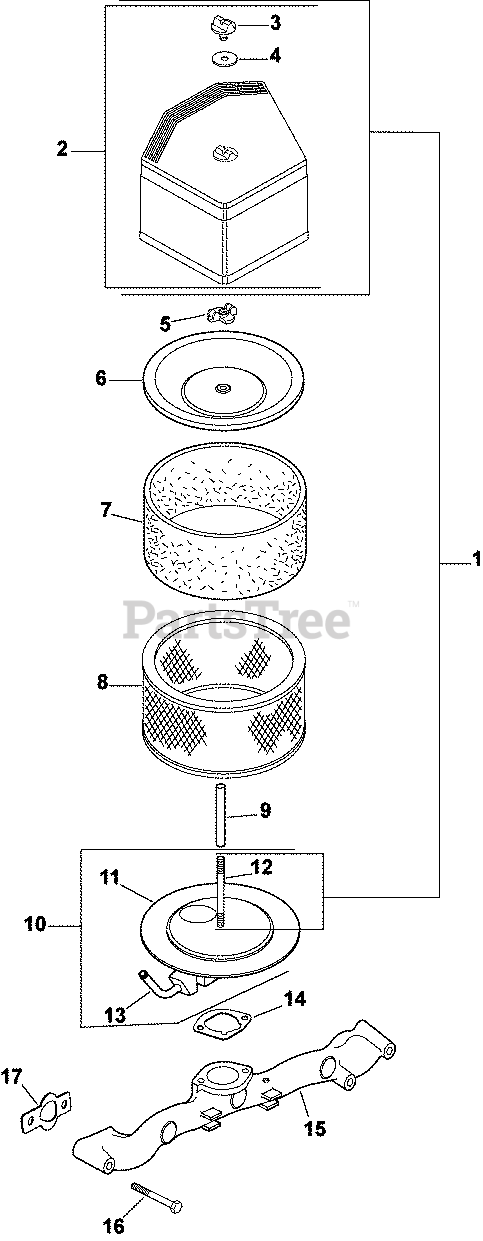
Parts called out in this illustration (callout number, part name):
1	KIT, AIR CLEANER (WAWB)
2	KIT, AIR CLEANER COVER
3	KNOB, COVER
4	GASKET, AIR CLEANER COVER KNOB
5	NUT, WING
6	COVER, INNER AIR CLEANER
7	ELEMENT, PRE-CLEANER
8	ELEMENT, AIR CLEANER - Also available Retail Packaged 45 883 02-S1 Air Filter Kit
10	ELBOW, AIR CLEANER (WAWB)-USE 24 054 31-
11	ELBOW, AIR CLEANER - (#2405431S)
12	STUD, M6X1.0X93MM
14	GASKET, AIR CLEANER BASE
15	MANIFOLD, INTAKE
16	SCREW, FLG M6X1.0X55
17	GASKET, INTAKE MANIFOLD USE 24 041 79-S
